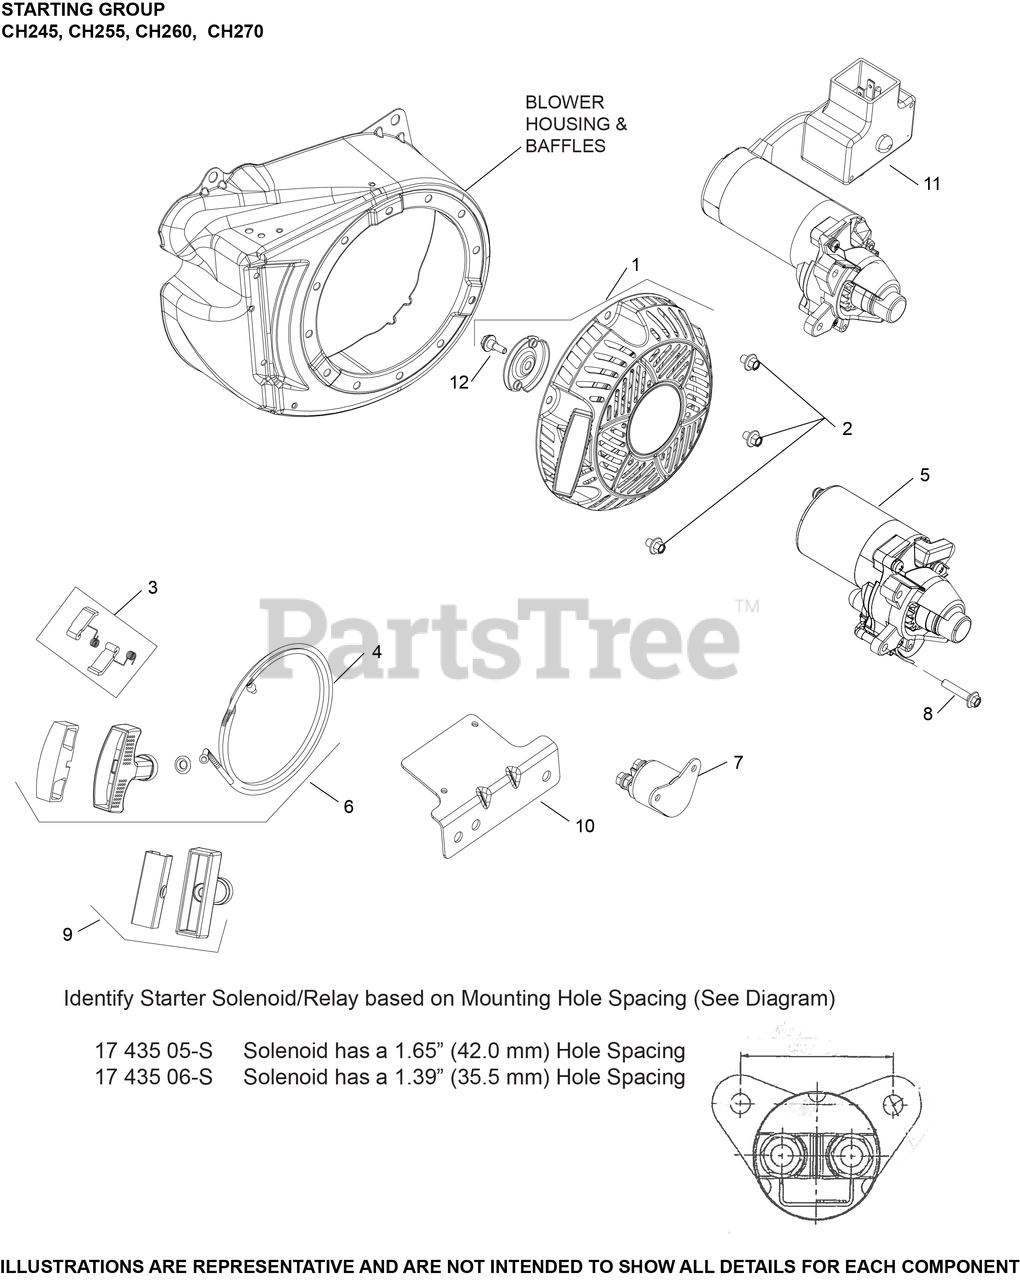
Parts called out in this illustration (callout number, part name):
1	RETRACTABLE STARTER ASSEMBLY
2	SCREW, M6 X 8 HEX FLANGE HEAD (CKY)
3	KIT, PAWL REPAIR
4	ROPE, STARTING
6	KIT, STARTER ROPE W/HANDLE
12	SCREW, SHOULDER (M5) (CKY)
